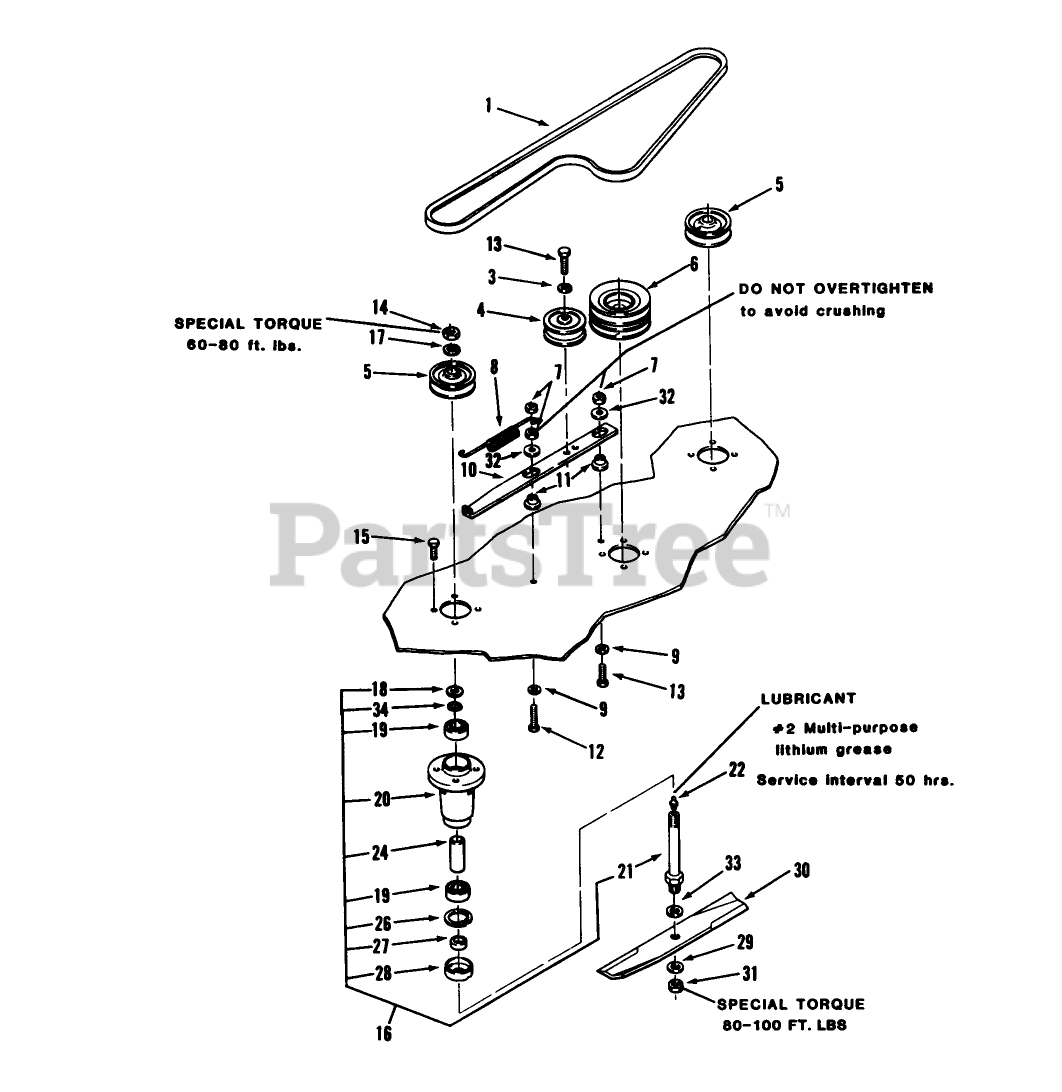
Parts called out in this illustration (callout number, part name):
1	V-BELT
3	LOCKWASHER
4	PULLEY-IDLER
5	PULLEY
6	PULLEY CENTER
7	NUT
8	SPRING-EXTENSION
9	WASHER
10	BAR-IDLER SUPPORT
11	SPACER-BUSHING
12	Bolt
13	Bolt
14	Nut
15	Bolt
16	Spindle Assembly (Incl. Ref. #18-21, 24, 28, & 34)
17	Lockwasher
18	Washer
19	BEARING-BALL
20	HOUSING-SPINDLE
21	SHAFT-SPINDLE
22	Zerk
26	Ring-Snap
27	SPACER-BLADE
28	CUP-SPINDLE
29	Washer
30	S/A BLADE KIT
31	Nut
32	WASHER
33	Washer
34	O RING
